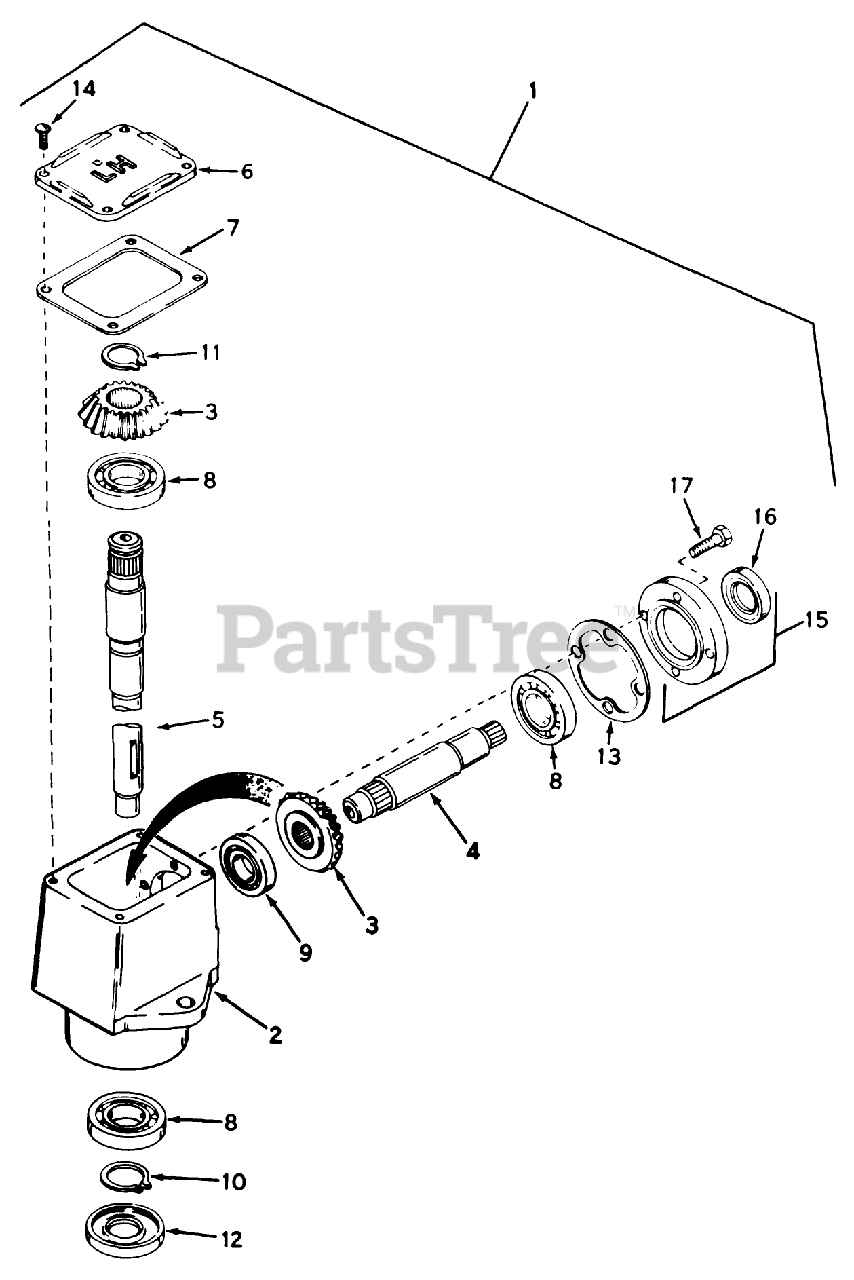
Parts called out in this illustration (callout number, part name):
1	Head Assembly-Left Hand (Incl. Ref. #2-15)
2	Housing
3	Bevel Gear
4	Shaft-Input
5	Shaft-Output
6	Cover
7	Gasket
8	Bearing
9	Bearing
10	Ring-Snap
11	Ring-Snap
13	Gasket
14	Screw
15	Cap Seal Assembly (Incl. Ref. #13 16)
16	Oil Seal
17	Ring Set (STD)
